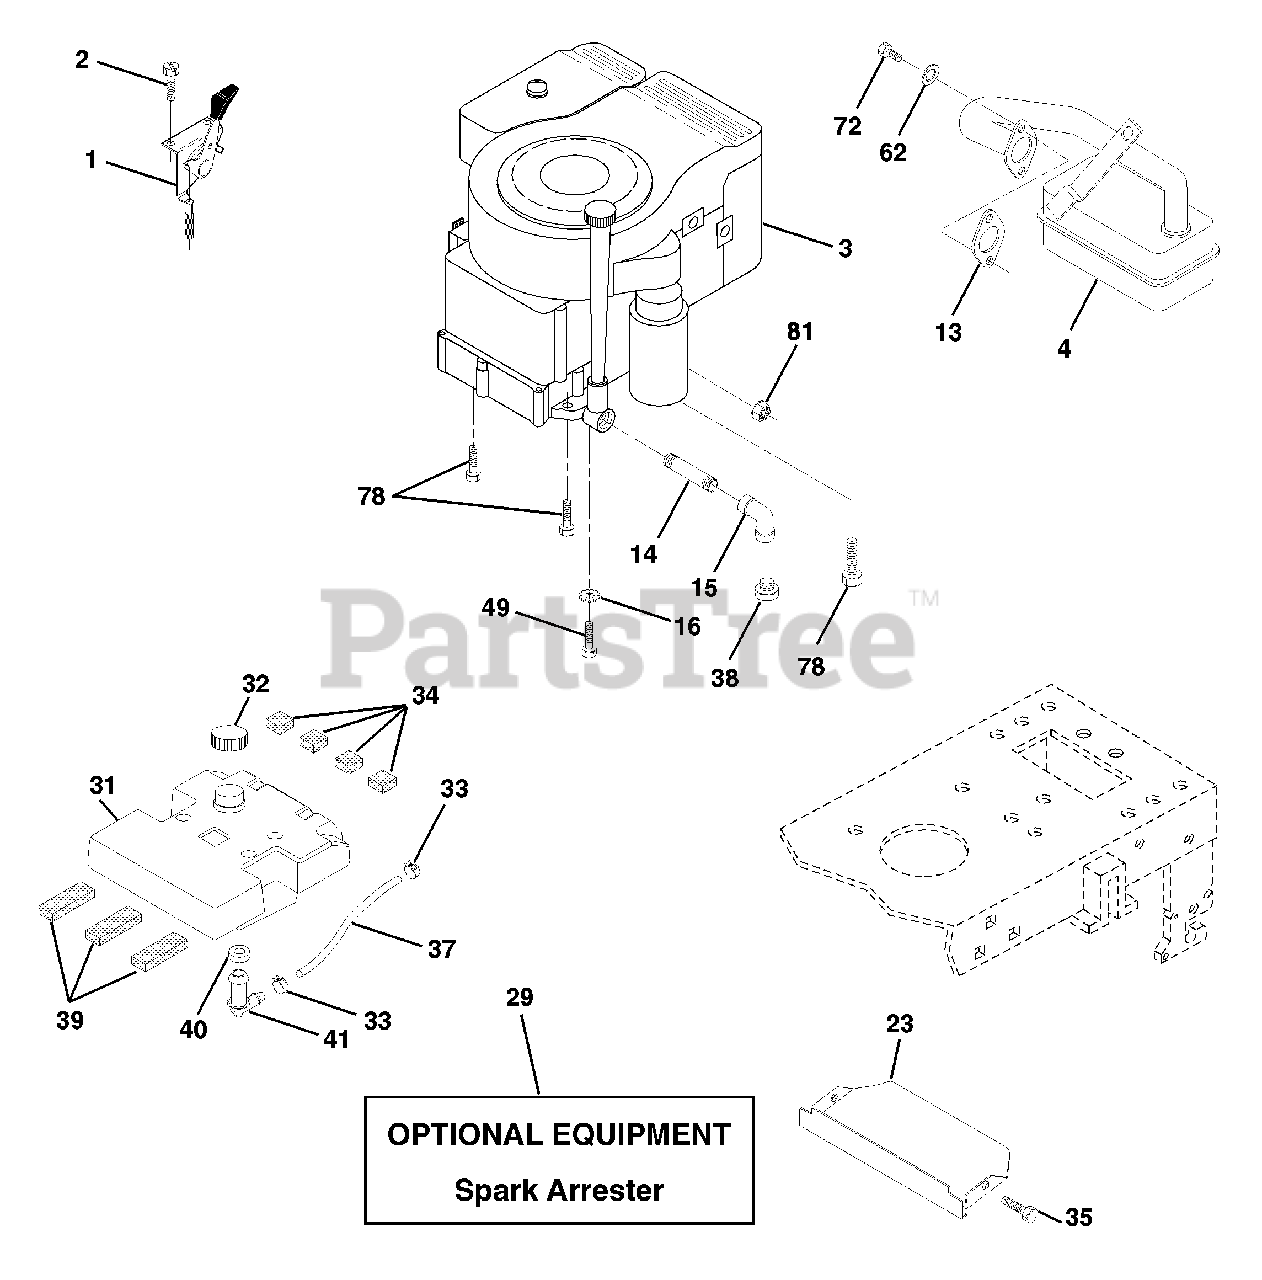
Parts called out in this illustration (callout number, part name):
1	Control Th/ch 23 5 LH Flag
2	Screw Hex Thd Cut 1/4-20x5/8 T
4	Muffler LT B&S Exhaust
13	Gasket Eng 1 313 Id Tin Plated
14	Nipple Pipe 3/8 Npt X 3"
15	Elbow Std 90 Degree 3/8-18 Npt
16	Washer Lock Ext Tooth 3/8
23	Shield Brn/Dbr Guard
29	Kit Spark Arrestor (Flat Scrn)
32	Cap Asm Fuel W/sym Vented
33	Clamp Hose Black
34	Pad Spacer 1 x 1 x 1 Blk
35	Screw
37	Line Fuel 7.5"
38	Plug Oil Drain (Order From Engine Manufacturer)
39	Pad Spacer 1.75 x .75 x .06
40	Bushing
41	Stem Tank Fuel
49	Screw
62	Washer Lock Hvy Hlcl Spr 5/16
72	Screw Hexhd Cap 5/16-18x 3/4
78	Screw Thdrol 3/8-16x1-1/4 TYTT
81	Nut Flange 1/4-20 Starter Nut
